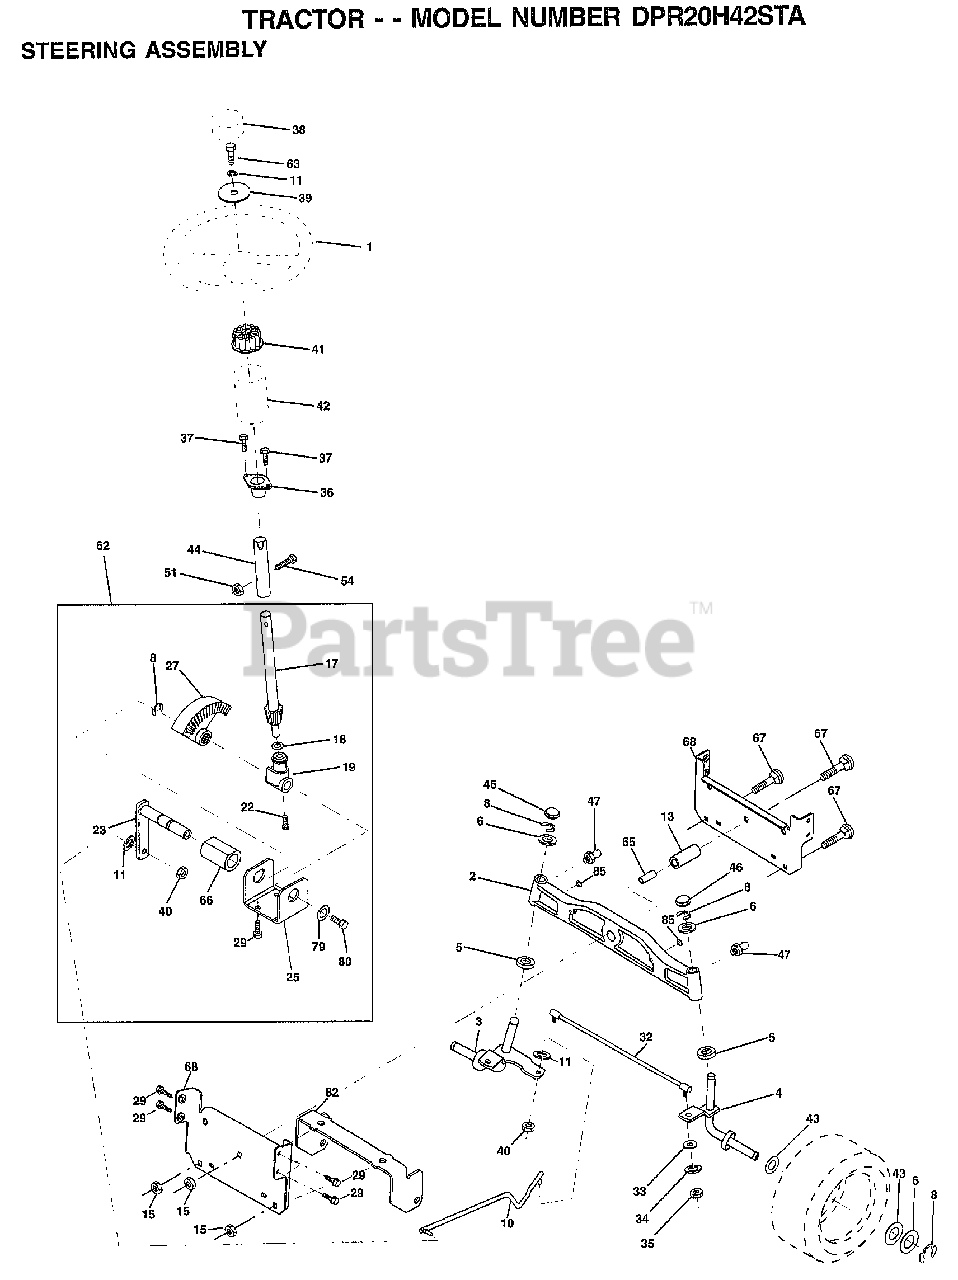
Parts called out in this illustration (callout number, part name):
1	WHEEL.STEERING
2	AXLE ASSY
3	SPINDLE ASM
4	SPINDLE ASM
5	WASHER .T
6	WASHER
8	RING
10	LINK DRAG
11	LOCKWASHER
13	SPACER BEARING
15	NUT.HXFLG.LOCK.
17	SHAFT ASM STEERIN
18	THRUST WASHER
19	SUPPORT.SHAFT.STEER
22	SCREW.HX.WSH.HD
23	SHAFT.ASM.PITMAN
25	BRKT-STEERING
27	GEAR SECTOR
29	SCREW
32	ROD TIE
33	WASHER M
34	LOCKWASHER
35	CROWNLOCK NUT
36	BUSHING.STEERING
37	"SCREW-TT,10-32 FL"
38	INSERT.CAP.STRG.WH
39	WASHER
40	GRIPCO NUT
41	ADAPTOR.WHEEL.STG
42	BOOT.STEERING.DASH.P/L
43	WASHER
44	EXT SHAFT STEERIN
46	CAP
47	ZERK M
51	NUT
54	BOLT
62	KIT.STEER.ASM
63	BOLT
65	"SPACER BRCAE,AXLE"
66	"BEARING-ARM,PITMA"
67	BOLT RDHD 3/8-16
68	BRACE AXLE
79	WASHER
80	BOLT.HX.NYLON3/8-16X3/
82	BRKT SUSP CHASSIS FRT
85	XMAS TREE FASTNER
